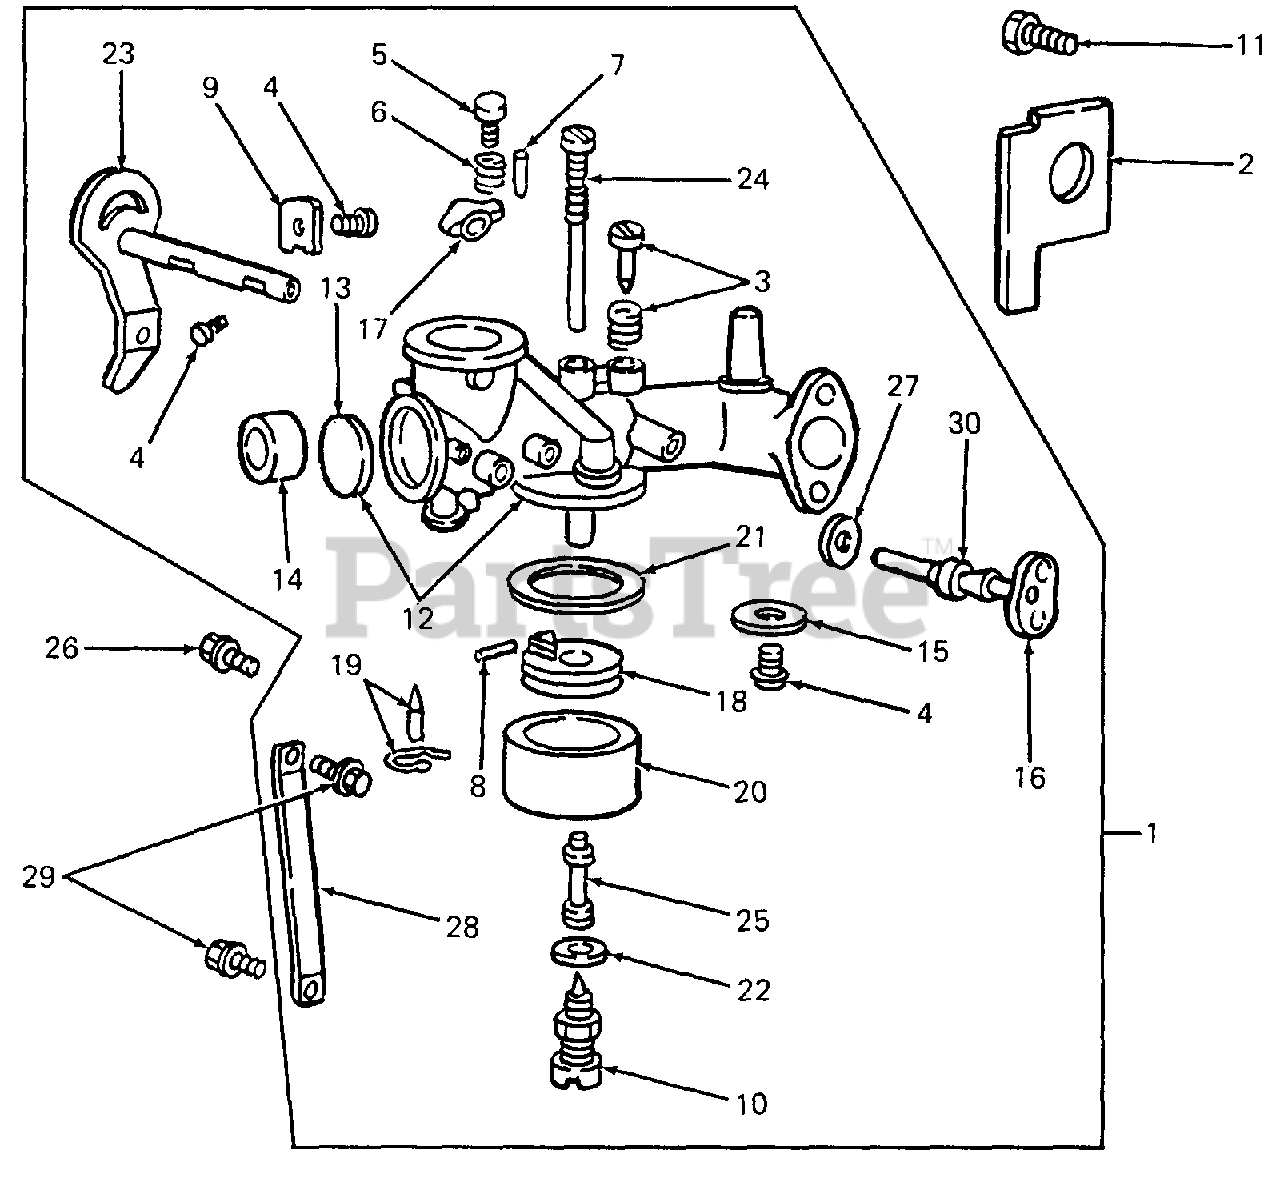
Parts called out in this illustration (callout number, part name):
1	Carburetor Assembly
2	Gasket, Carburetor Mounting
3	Valve Assy, Carburetor Idle
4	Screw, Throttle & Choke Valve Mtg Sems
5	Screw, Machine Fill Hd, #8-32 X .62 Lg
6	Spring, Throttle Adjustment
7	Pin, Throttle Stop
8	Pin, Float Hinge
9	Valve, Choke
10	Valve, Needle
11	Screw, Carburetor Mounting
12	Body Assy, Carburetor
13	Plug, Welch
14	Venturi, Carburetor
15	Valve, Throttle
16	Shaft & Lever, Throttle
17	Stop, Throttle
18	Float, Carburetor
19	Valve, Fuel Inlet
20	Bowl, Fuel
21	Gasket, Float Bowl
22	Washer, Float Bowl
23	Shaft & Lever, Manual Choke
24	Nozzle, Carburetor
25	Screw, Nozzle
26	Screw, Control Casing
27	Washer, Foam
28	Bracket, Carburetor
29	Screw, Carburetor
30	Seal, Throttle Shaft
